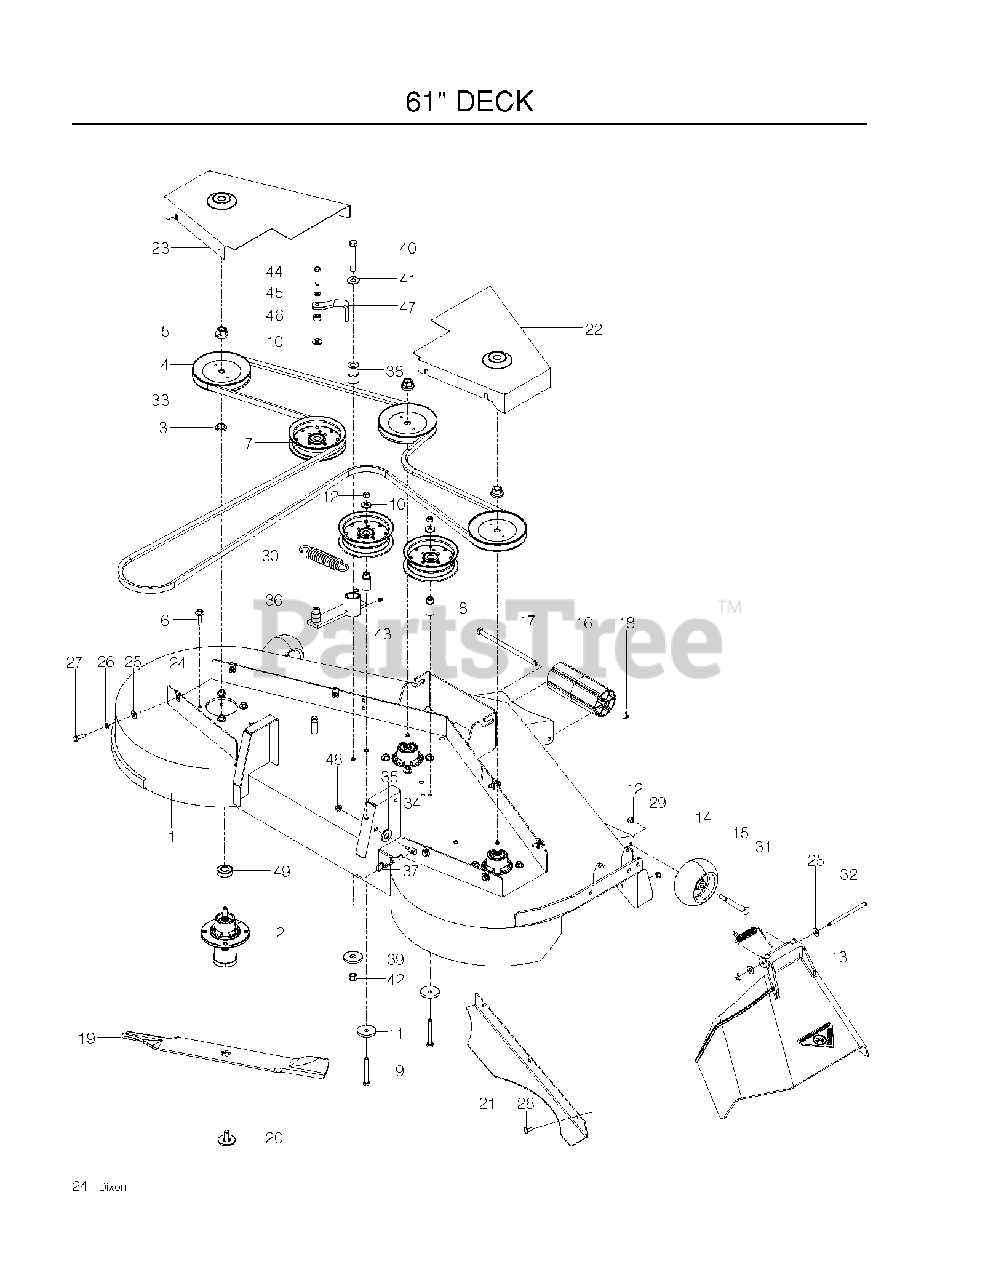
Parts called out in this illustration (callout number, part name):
1	DECK W/DECALS - RAM 61
2	MANDREL.DECK.ASSEMBLY
3	WASHER-SPACER
5	LOCKNUT - 9/16
6	WASHER HEAD SCREW
7	PULLEY, IDLER
8	IDLER BUSHING
9	HCS 3/8C X 3
10	WASHER 3/8 FLAT
11	SPINDLE WASHER
12	NUT 3/8-16 NYLOC
13	DISCHARGE CHUTE 61"
14	GAUGE WHEEL
15	SHOULDER BOLT 1/2X2-5/8 ZD SPE
16	NOSE ROLLER 48"
17	NOSE ROLLER ROD
18	COTTER PIN 1/8 X 3/4
19	BLADE, 21"
20	BLADE BOLT ASSY-7/16" TB REPL
21	CONFINEMENT PLATE 61
22	SHIELD, BELT 61 BLUE RH
24	U-CLIP 5/16-18 NUT RETAINER
25	WASHER 5/16 FLAT
26	WASHER 5/16 LOCK
27	HCS 5/16C X 1
28	CARRIAGE BOLT 5/16C X 5/8"
29	NUT 5/16 NYLOC
31	SPRING - TORSION
32	PIN-CLEVIS 5/16 DIA X 5.19 ZD
33	V-BELT, 161B
34	STUD.FASTNER.W/ANTI-ROTATE
35	WASHER 5/8 FLAT
36	IDLER ARM
37	HAIRPIN #4
38	PIVOT BUSHING
39	WASHER, SUPPORT
40	HCS 1/2C X 3 1/4
41	WASHER 1/2 FLAT
42	NUT 1/2-13 HEX NYLOC ZD
43	ZERK
44	HCS 3/8-16 X 1 3/4 GR5
45	SLW 3/8 STD
47	GUIDE, BELT
48	5/16-18 NYLOC FLANGE NUT
49	BEARING, BALL
